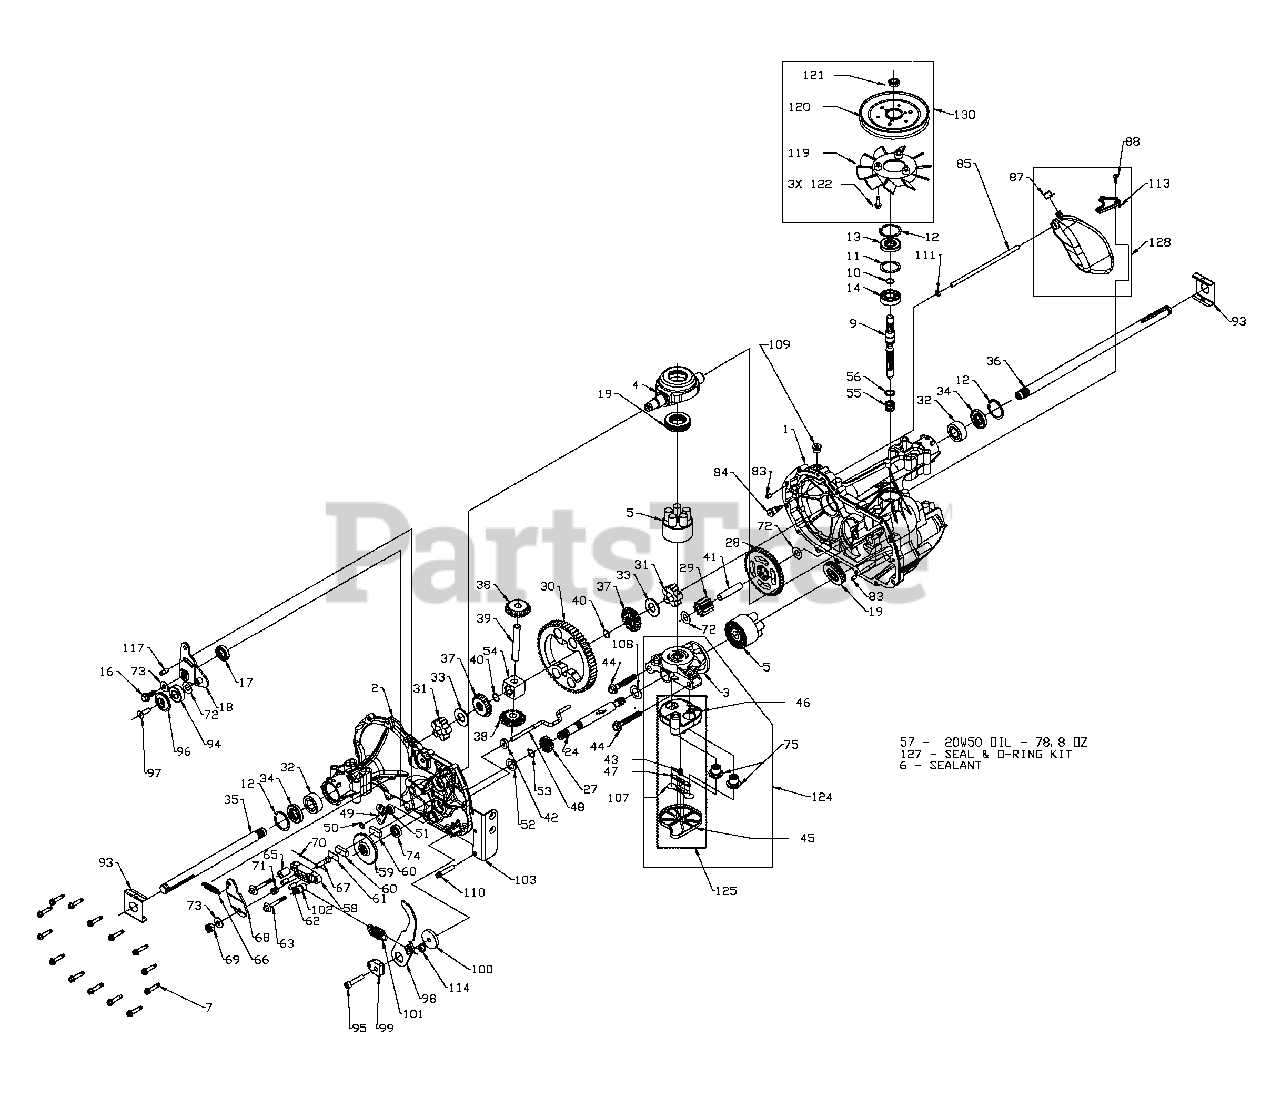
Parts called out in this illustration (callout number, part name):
9	SHAFT, INPUT
10	RING - RETAINING
12	RING - RETAINING
13	SEAL, Lip, .67 x 1.58 x .276
14	BALL BEARING
32	OUTBOARD SLEEVE BEARING
34	LIP SEAL, Axle Seal
35	AXLE SHAFT - RH
36	AXLE SHAFT - LH
55	SPRING - HELICAL COMPRESSION
101	HYDRO RETURN SPRING
119	FAN, 6", 10 BLADE
128	EXPANSION TANK KIT
130	FAN/PULLEY KIT
